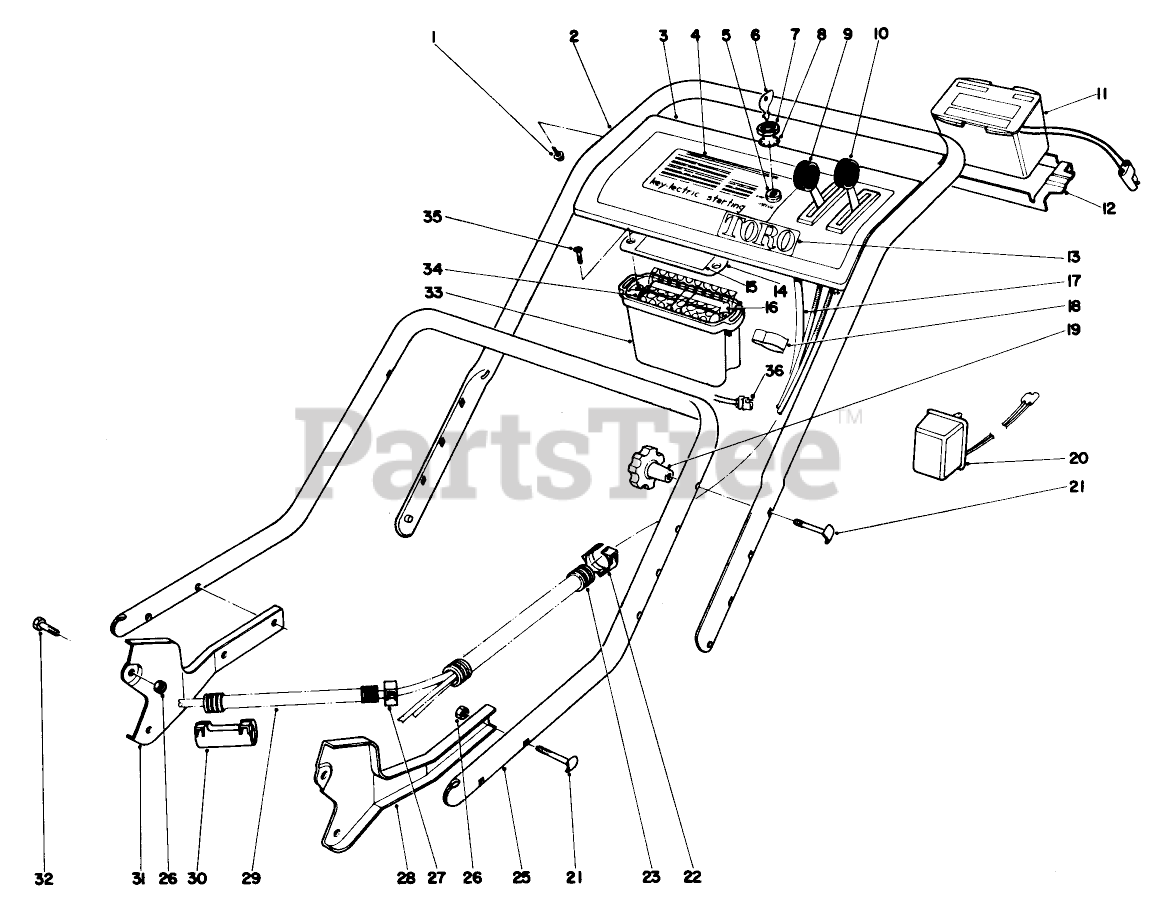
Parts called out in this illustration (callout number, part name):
1	SCREW-HWHTF
2	Upper Handle
3	Control Plate
4	Decal Control Plate
5	SWITCH-STARTER
6	Key
7	NUT-HH
8	WASHER-TOOTH, INTERNAL
9	SPEED CONTROL
10	Control Traction
11	Battery
12	Adapter
13	Decal-Toro
14	Cover
15	Decal
16	Battery Pack
17	Wiring Harness
20	Charger
21	HANDLE SCREW
22	FITTING-RING
23	Upper Wiring Harness Cover
25	Lower Handle
26	Nut
27	RING FITTING
28	Latch Handle L.H.
29	Lower Wiring Harness Cover
30	Breakout Fitting
31	Latch Handle R.H.
32	SCREW-HH
33	Container Pack
34	Spacer
36	Plug & Wire
